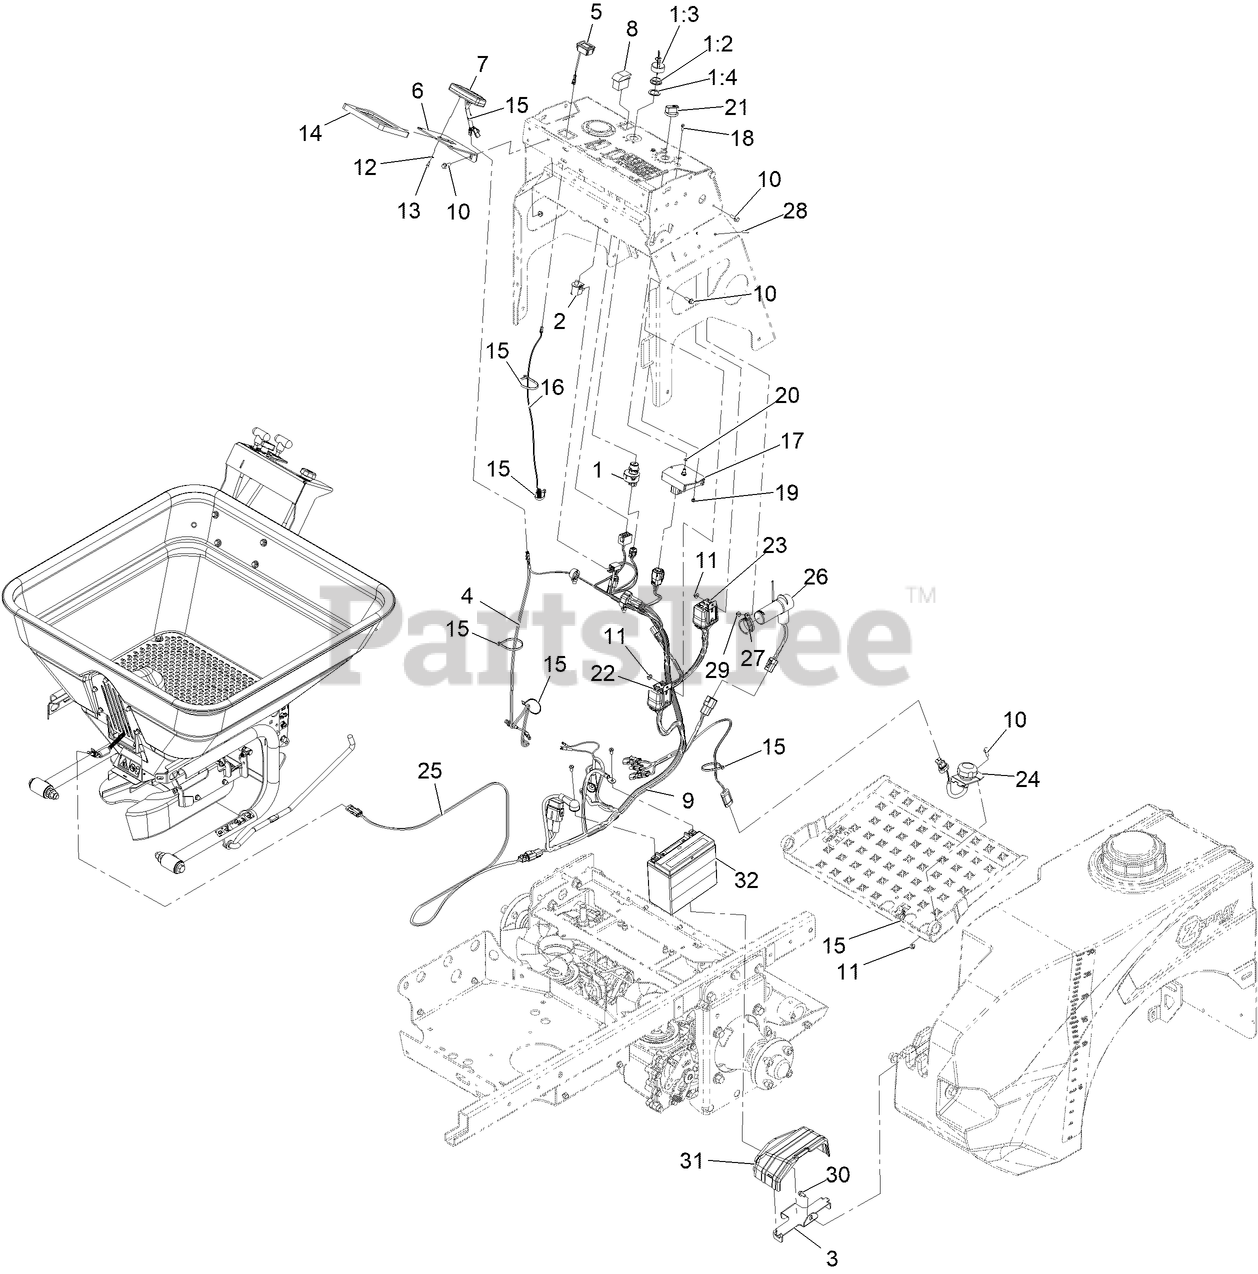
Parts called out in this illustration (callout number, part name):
1	IGNITION SWITCH ASM
1:2	NUT-MOUNTING
1:3	IGNITION KEY SET
1:4	WASHER-BACKUP
2	SWITCH-BAIL
3	STRAP-BATTERY
4	Cable-Trail Tech, Sensor
5	METER-TACH/HOUR
6	MOUNT-DISPLAY
7	HEAD ONLY, STRIKER
8	SWITCH-ROCKER
9	HARNESS
10	Screw-HHF
11	Nut-Hex Flange
12	WASHER-FLAT
13	SCREW-HSH
14	PAD-DISPLAY MOUNT
15	TIE-CABLE
16	WIRE-TACHOMETER
17	CONTROLLER-MOTOR, SPREADER
18	SCREW-HHF, SERRATED
19	NUT-HEX, NYLOCK
21	KNOB-INDICATING
22	DECAL-FUSE,SOLID STATE
23	DECAL-FUSE,MAIN
24	SWITCH-FOOT
25	HARNESS-SPREADER MOTOR
26	HARNESS-CAPACITOR
27	CLAMP-R, CUSHION
28	SCREW-HH
29	Nut-Hex Flange
30	SCREW-HWH
31	COVER-BATTERY
32	BATTERY-AGM
